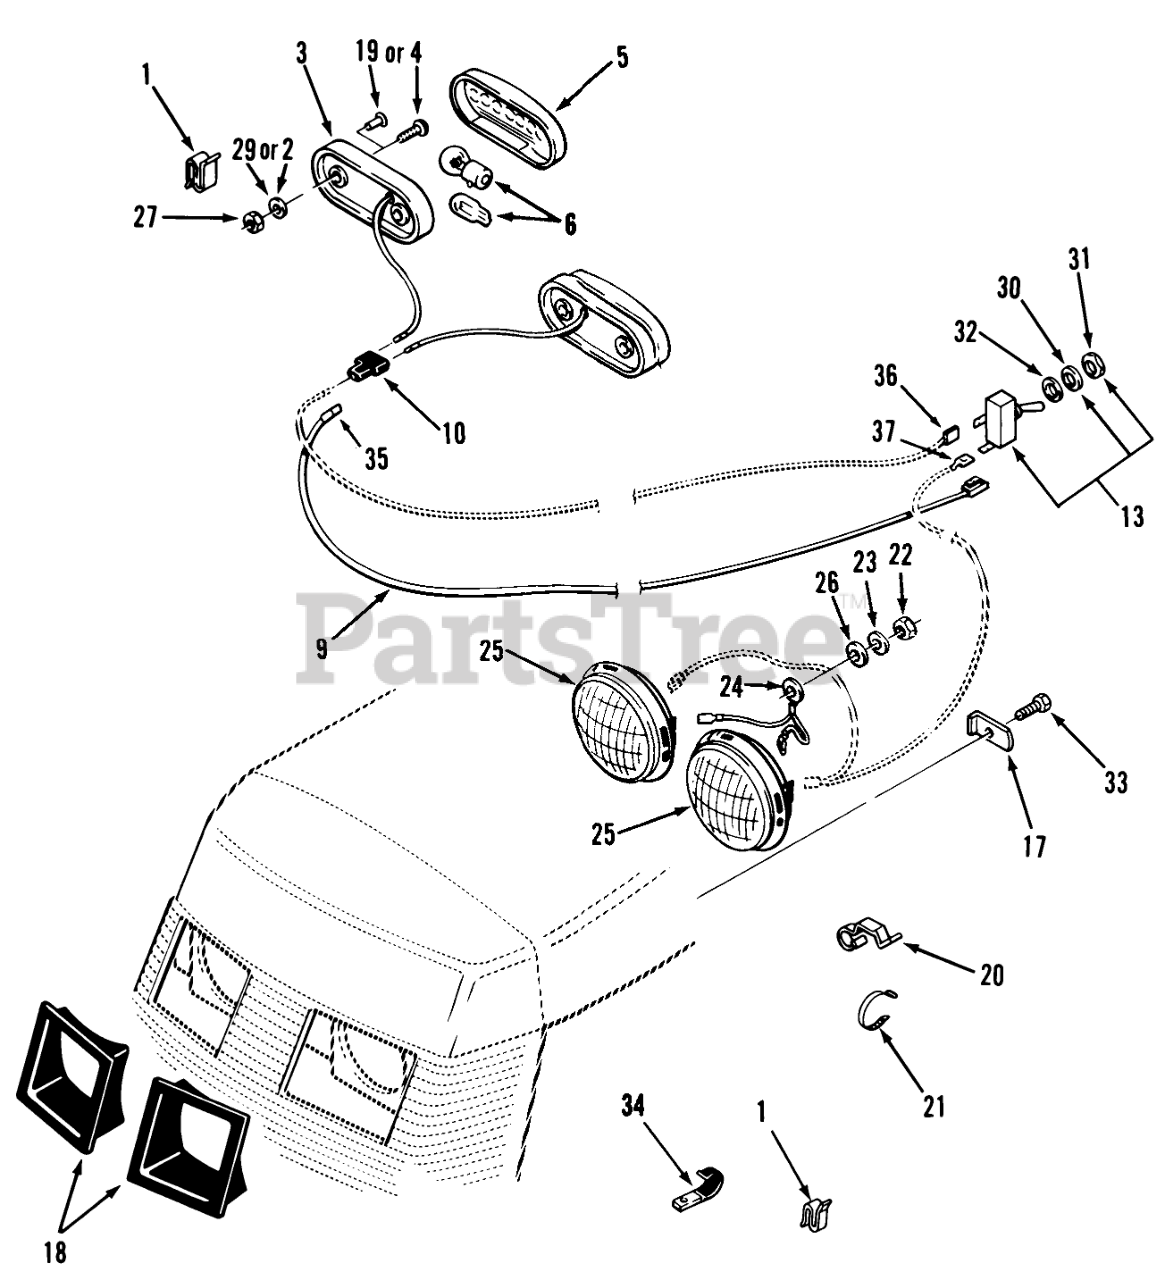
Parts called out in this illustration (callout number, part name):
1	SPEED CLIP
2	Lockwasher
3	BASE-TAIL LIGHT
4	Screw
5	LENS-TAIL LIGHT
6	Bulb
6	LIGHT BULB
9	WIRE TAIL LIGHT
10	CONNECTOR 3 WIRE
13	SWITCH-LIGHTS
17	LOCK-HEADLIGHT
18	HEADLIGHT BEZEL ASSY.(SERVICE)
19	RIVET-4
20	CLIP-WIRE
21	PLASTIC TIE
22	Nut
23	Washer-Lock
24	LIGHT GROUND WIRE
24	ASSY GROUND WIRE
25	HEAD LAMP
25	HEADLAMP
26	WASHER 5/16 SAE
27	Nut
29	WASHER
30	TAB-WASHER
31	NUT-HEX
32	Washer
33	Bolt
34	CLIP
35	Sur-Plug
36	TERMINAL 10
37	Terminal
